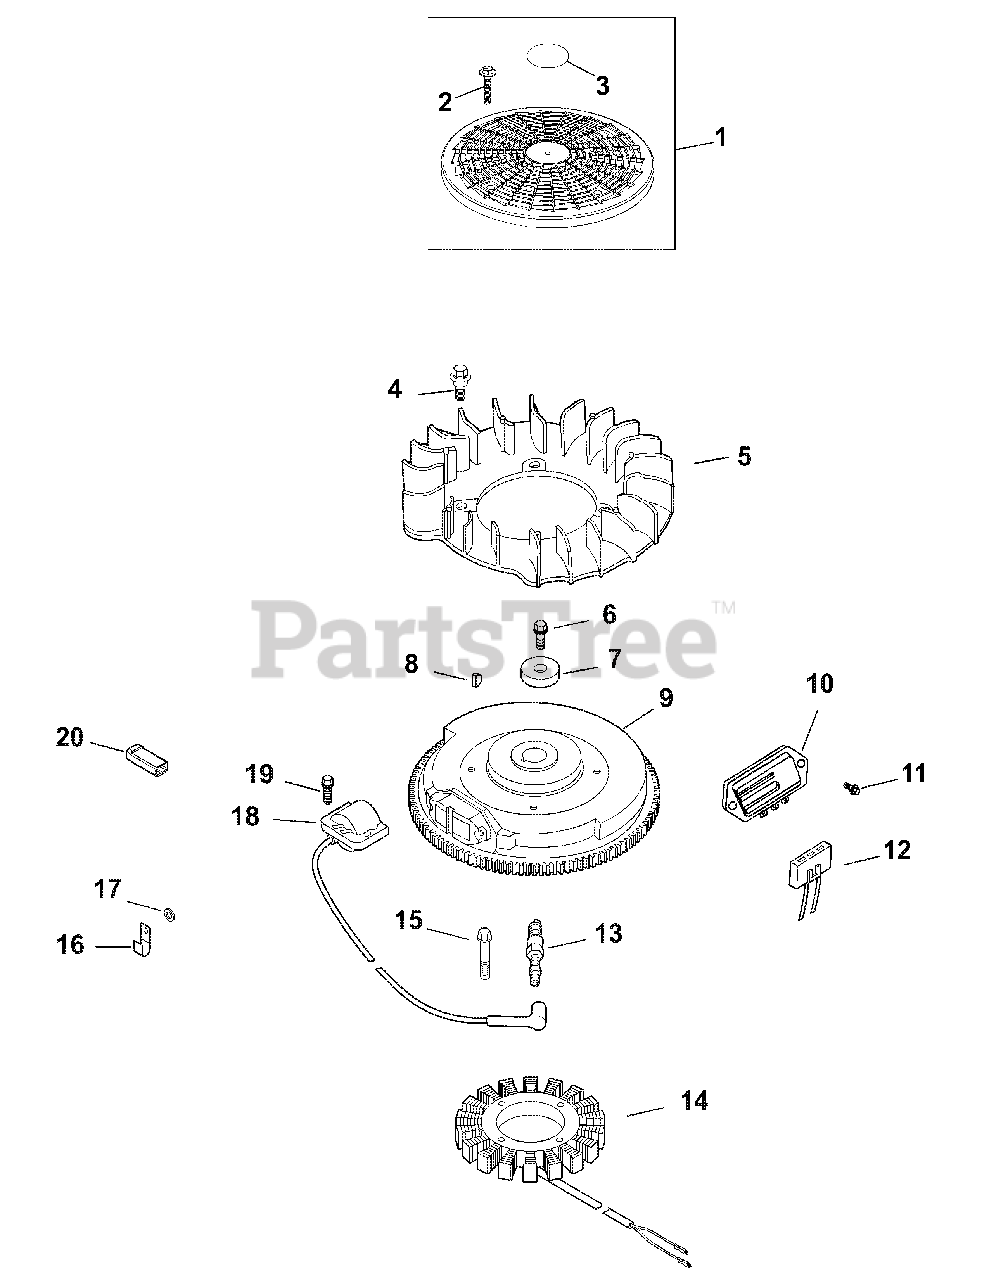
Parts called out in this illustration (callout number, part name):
1	Kit, Grass Screen
2	Screw, Flg Sems M4 x 0.7 x 25
3	Decal, Grass Screen
4	Bolt, Shoulder
6	Screw, FLG M10X1.5X45
7	Washer, Flat 13/32"
8	Key, 3/16" x 5/8"
10	Rectifier-Regulator
11	Screw, Hex Flange Hi-Lo
12	Connector (3 Contact)
13	Plug, Spark
14	Kit, 15 Amp Stator
15	Screw, THD FRM M5 x 0.8 x 25
16	Clip, Cable
17	Washer, Flat, 1/4"
18	Kit, Module, Ignition (CDI Fixed)
19	Screw, FLG THD FRM M5 x 0.8 x 20
20	Connector (1 Contact)
